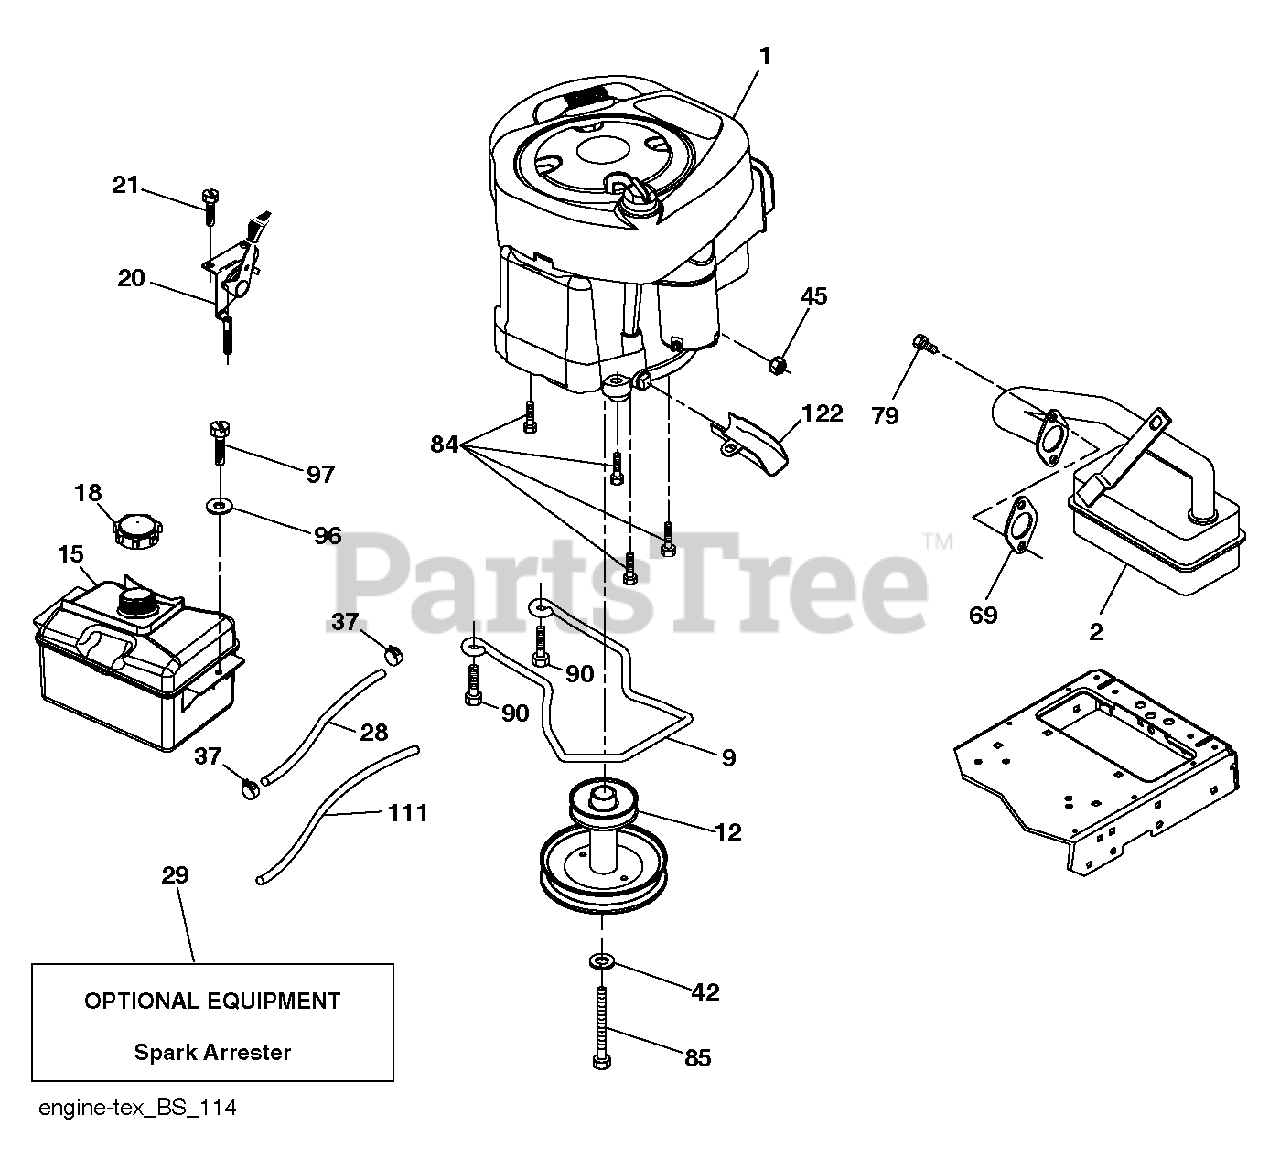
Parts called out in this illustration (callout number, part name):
2	MUFFLER.LT.BRIGGS.14HP.IC/OHV
9	KEEPER.BELT.ENG.3.25"2BOLT.PNT
12	PULLEY.ENGINE.5.0.PD
15	TANK.ASM.1.5GAL.FRT.W/CAP.EPA
18	CAP.FUEL.2 WAY VENT
21	SCREW.#10 X 0.750.BOS (2 2)
28	LINE.FUEL.20"FRONT.EMI
29	KIT.SPARK ARRESTOR(392390 B&S)
37	HOSE CLAMP
42	LOCKWASHER
45	NUT
79	SCREW.SOCKET HD.5/16-1
84	SCREW.3/8-16
85	Hex Bolt, 7/16-20 X 4-1/4" Grade 5
90	SCREW 3/8-16X1
96	WASHER
97	SCREW HEXWSHR 1/4-20X3/4
111	RP PURGE LINE
122	EXTENSION DRAIN OIL
